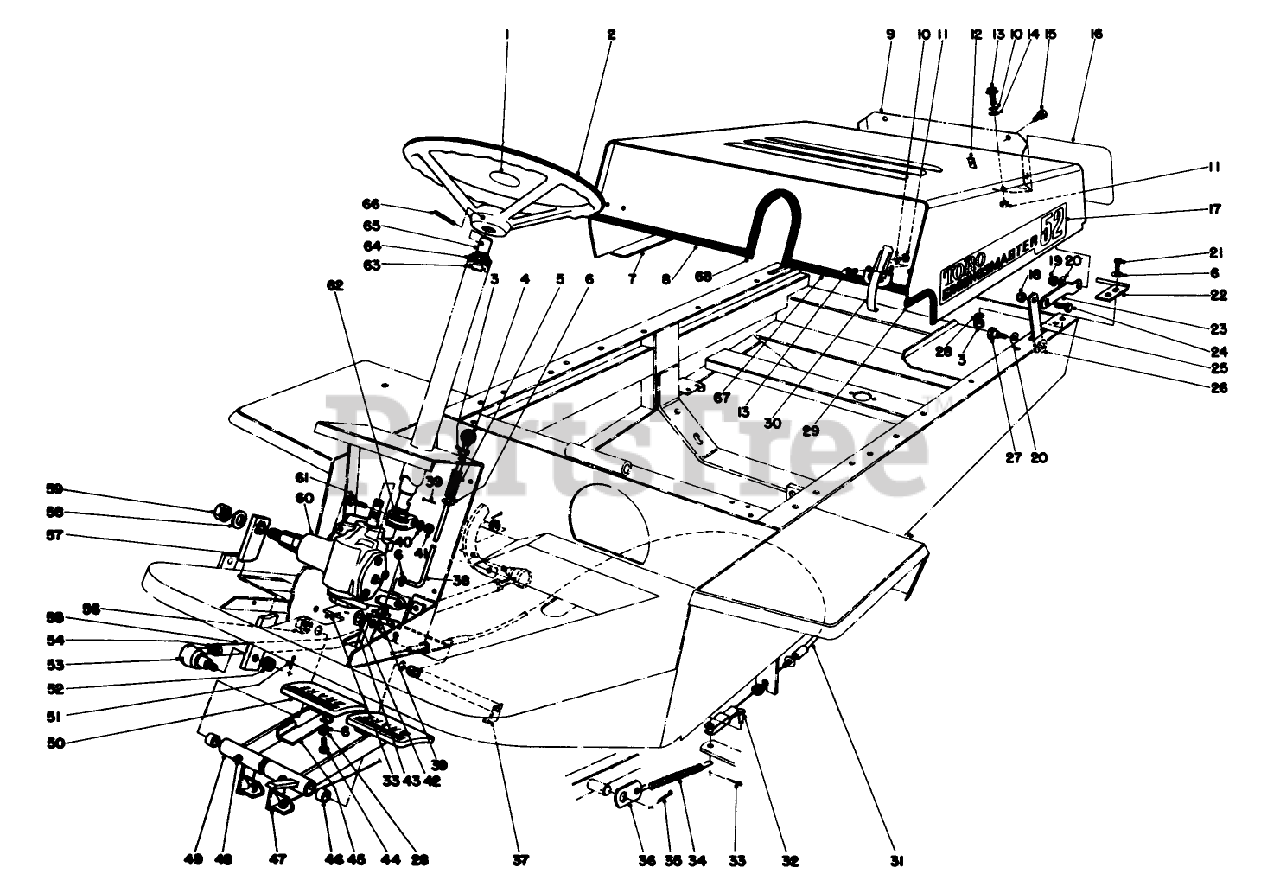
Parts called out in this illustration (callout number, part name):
1	STEERING WHEEL CAP
2	STEERING WHEEL
3	NUT-HEX
5	Spring
6	WASHER-FLAT
7	Hood
8	TRIM-HOOD
9	HOOD SCREEN B
10	WASHER-LOCK
11	NUT-HEX
12	NUT-CLIP,U
13	SCREW-SHWH
14	WASHER-FLAT
15	SCREW-PPHTF
16	S-LINK
17	GM-52 DECAL
18	NUT-HEX
19	NUT-HHF, WHIZ
20	WASHER-SPRING
21	SCREW-HH
22	PivotPin L.H.
23	Link Hood
24	SCREW-HH
25	Tie Hood
26	WASHER-FLAT
27	SCREW-SHOULDER
28	WASHER-LOCK
29	HOOD TRIM
30	HOOK TYPE CLAMP
31	RH BRAKE CABLE ASM
32	PIN-CLEVIS
33	PIN-COTTER
34	SPRING-EXTENSION
35	PIN-COTTER
36	BRAKE SPRNG STRAP R
38	Rod Brake Latch
39	PIN-COTTER
40	WASHER-LOCK
41	NUT-HEX
42	WASHER-FLAT
43	RACK WA
44	SCREW-HH
45	Latch Parking Brake
46	BUSHING
47	Brake Pedal L.H. (Incl. Ref. #46 & 48)
48	FITTING-GREASE
49	Brake Pedal R.H. (Incl. Ref. #46 & 48)
50	PAD-BRAKE
51	PIN-COTTER
52	NUT-SLOTTED
53	Socket Assembly R.H. (Incl. Ref. #52)
54	NUT-JAM
55	FRONT STEERING TUBE B
56	NUT-LOCK, NI
57	Pitman Arm
58	WASHER-LOCK
59	NUT-JAM
60	Steering Gear
61	7/16-14 X 1-3/4 BOLT
62	CLAMP STRG COUPLING
63	BALL BRG
64	COVER-DUST
65	STRG SHAFT WA
66	PIN-ROLL
67	HOOD TRIM
